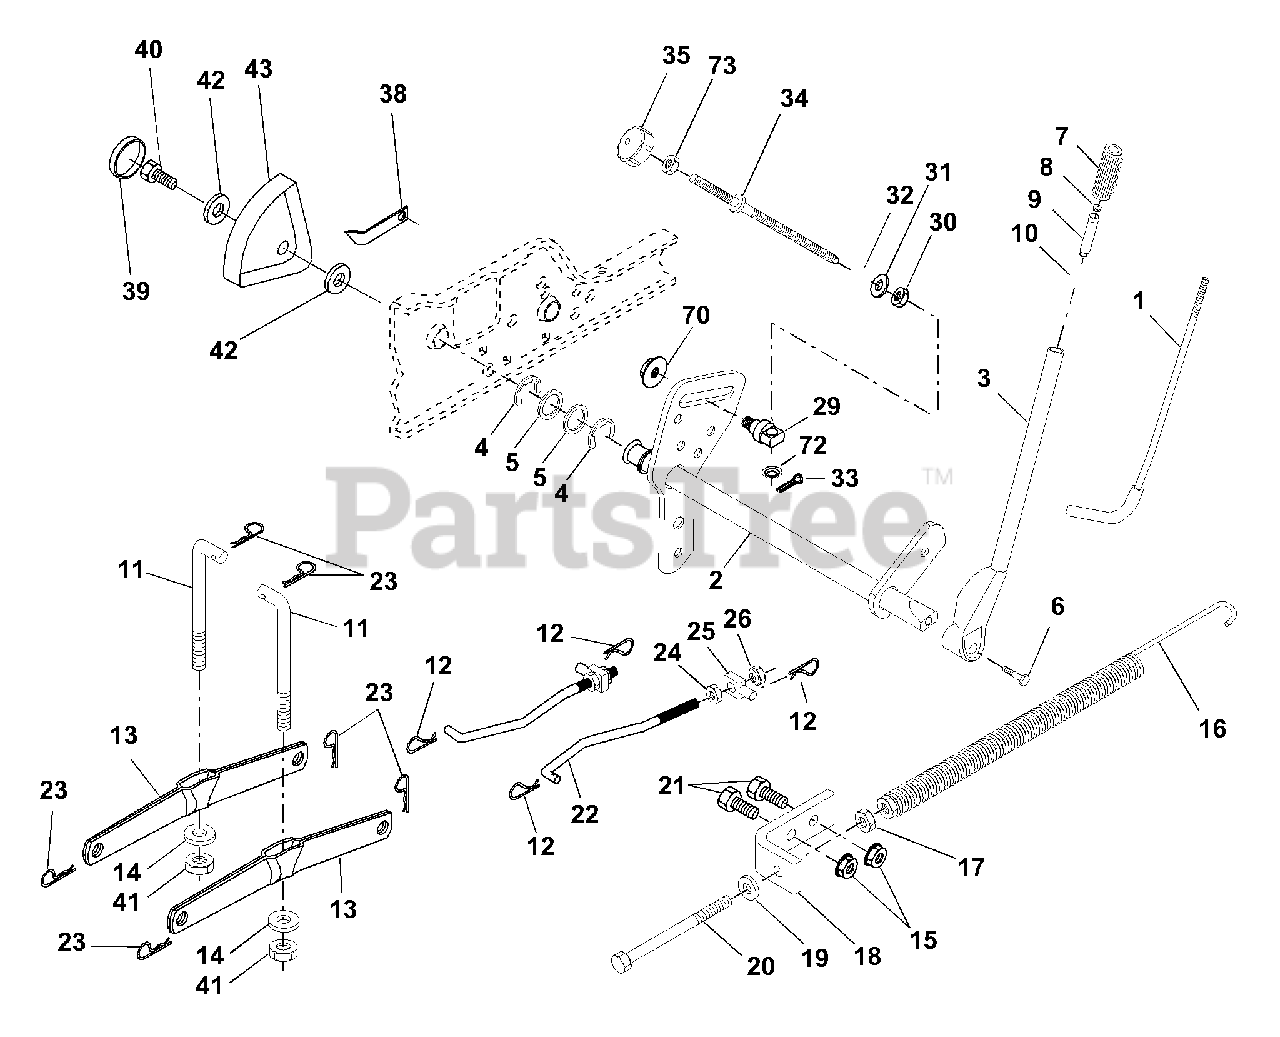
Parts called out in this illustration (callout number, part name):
1	Rod Asm., Lever
2	Shaft Asm., Lift Vgt
3	Lever Asm., Lift Rh
4	E-Ring Truarc #5133-87
5	Washer 29/32 x 1-1/4 x 16 Ga.
6	Bolt, Fin Hex 3/8-16 x 1-1/2
7	Grip, Handle Fluted
8	Button, Plunger
9	Plunger, Lever Lift
10	Spring 2-1/8"
11	Link Lift
12	Retainer, Spring
13	Arm, Suspension Vgt
14	Bearing
15	Nut, Crownlock 3/8-16 Unc
16	Spring Asm., Assist Lift
17	Nut, Hex Jam 3/8-16 Unc
18	Bracket, Spring Assist
19	Washer 13/32 x 13/16 x 16 Ga.
20	Bolt, Adjust Spring Assist
21	Bolt, Fin Hex 3/8-16 x 1
22	Link, Front
23	Retainer, Spring
24	Nut, Jam Hex 1/2-13 Unc
25	Trunnion
26	Nut, Crownlock 1/2-13 Unc
29	Trunnion, Infin Height
30	Nut, Special
31	Washer 13/32 x 5/8 x 16 Ga.
32	Spring, Compression Inf Hgt
33	Pin, Cotter 3/32 x 1/2
34	Rod, Adj Lift
35	Knob, Inf 3/8-16 Unc
38	Pointer, Height Indicator
39	Plug, Hole
40	Screw 5/16-18 x 1
41	Nut, Crownlock 3/8-24
42	Washer 11/32 x 1-1/2 x 10 Ga.
43	Scale, Indicator Height
70	Nut Hex Flange Lock
72	Nut Push Phos & Oil
73	Nut Hex Jam 3/8-16 Unc
